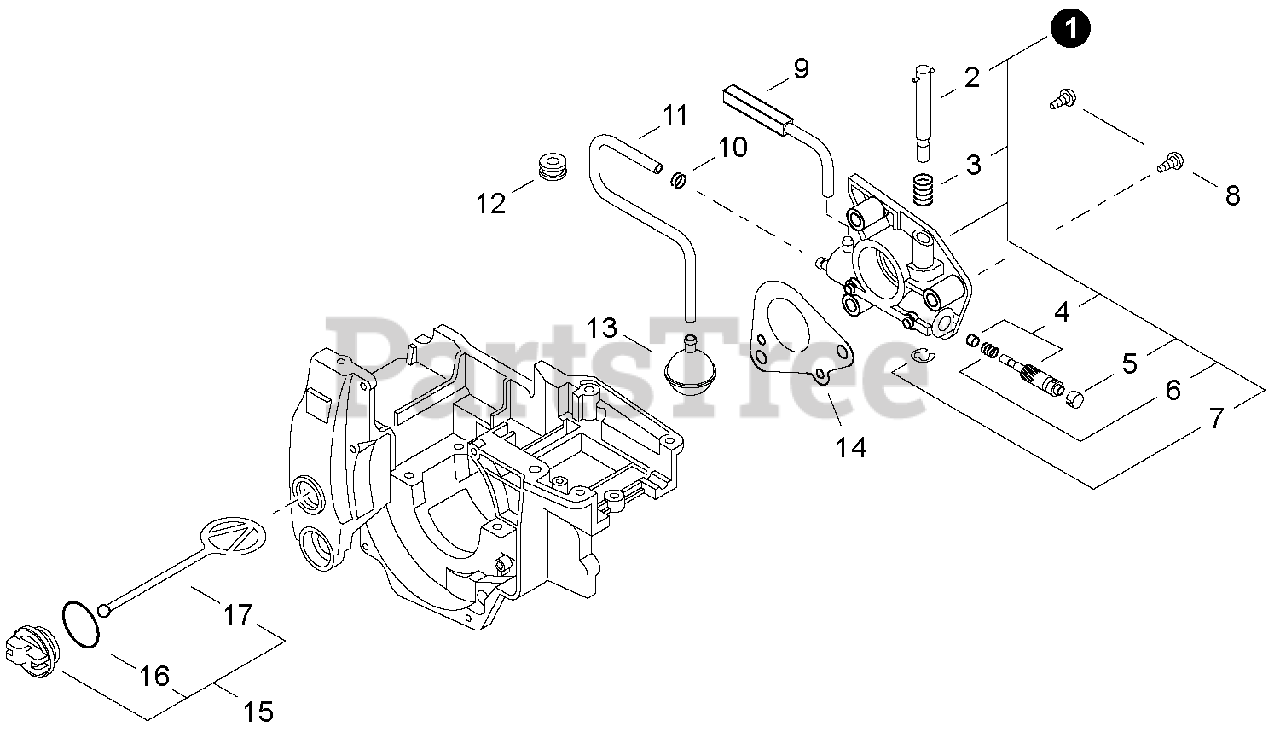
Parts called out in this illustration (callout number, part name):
1	AUTO-OILER ASSY
2	SCREW, ADJUSTER
4	PLUNGER ASSY
5	CAP, PLUNGER
8	SCREW 4×16
9	PIPE, OIL OUTLET
10	CLIP Ø6.5 MM
11	PIPE, OIL
13	FILTER, OIL
14	PLATE, SEAL
15	CAP ASSY, OIL
16	O-RING 25
17	CONNECTOR, CAP L= 60 MM
